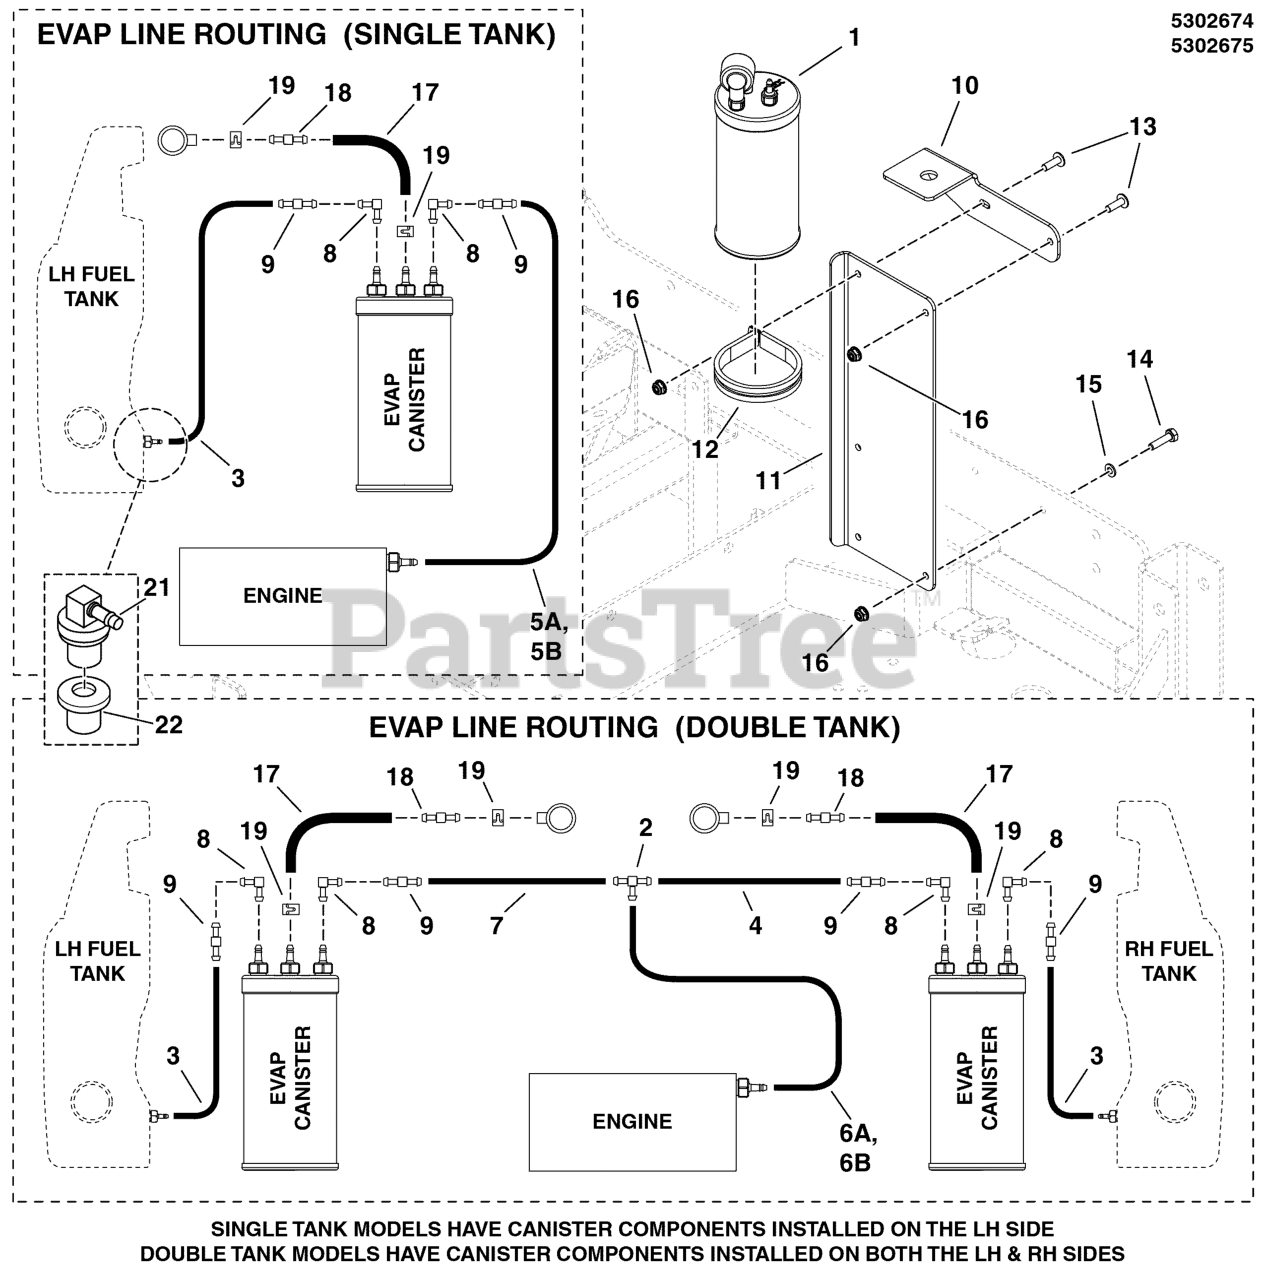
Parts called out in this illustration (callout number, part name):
1	* CNSTR, CARB, 6 GAL
2	FITTING, 3/16" TEE, BARB TYPE, HDPE
3	* HOSE, VAPOR, 5MM ID, 5.00 LG
4	HOSE, VAPOR, 5MM ID, 11.50 LG
7	HOSE, VAPOR, 5MM ID, 30.0 LG
8	* FITTING, 90 DEG, 3/16X3/16, SANTOPRENE
9	* FITTING, STRAIGHT, 3/16X3/16, PLASTIC
10	BRACKET, FUEL VALVE
11	* MOUNT, CAN, SIDE - BLK
12	* CLAMP, 3" ID, CUSHIONED, STAINLESS
14	BOLT, 1/4-20 X 1" GD5 CZ
15	WASHER, 1/4 SAE
16	* NUT, 1/4-20 HEX NYLOCK FLANGE
17	* HOSE, FORMED, EVAP CANISTER
18	* FITTING, STRAIGHT, 10MMX10MM, PLASTIC
19	* CLAMP, HOSE
20	DECAL, EPA CERT, ZTR
21	REMOTE VENT ASSEMBLY
22	GROMMET
